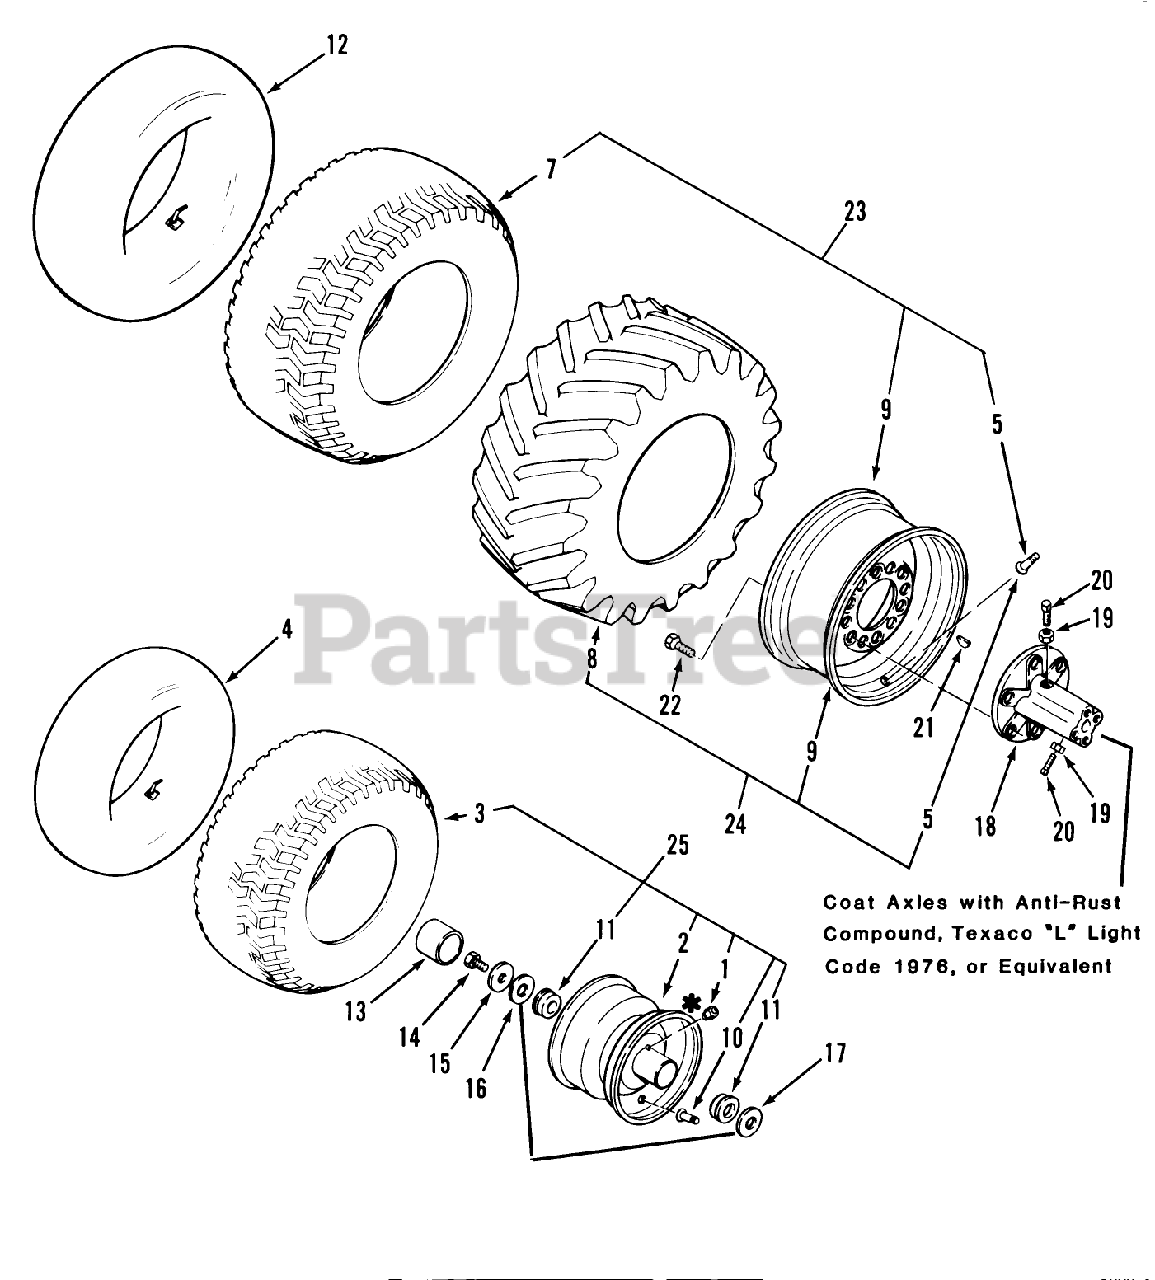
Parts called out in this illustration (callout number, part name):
2	Front Wheel (Includes Item 1)
4	TUBE-TIRE
8	Rear Tire 27 x 8.50-15 Cleat
10	VALVE
15	WASHER
16	WASHER
22	BOLT-LUG, WHEEL
